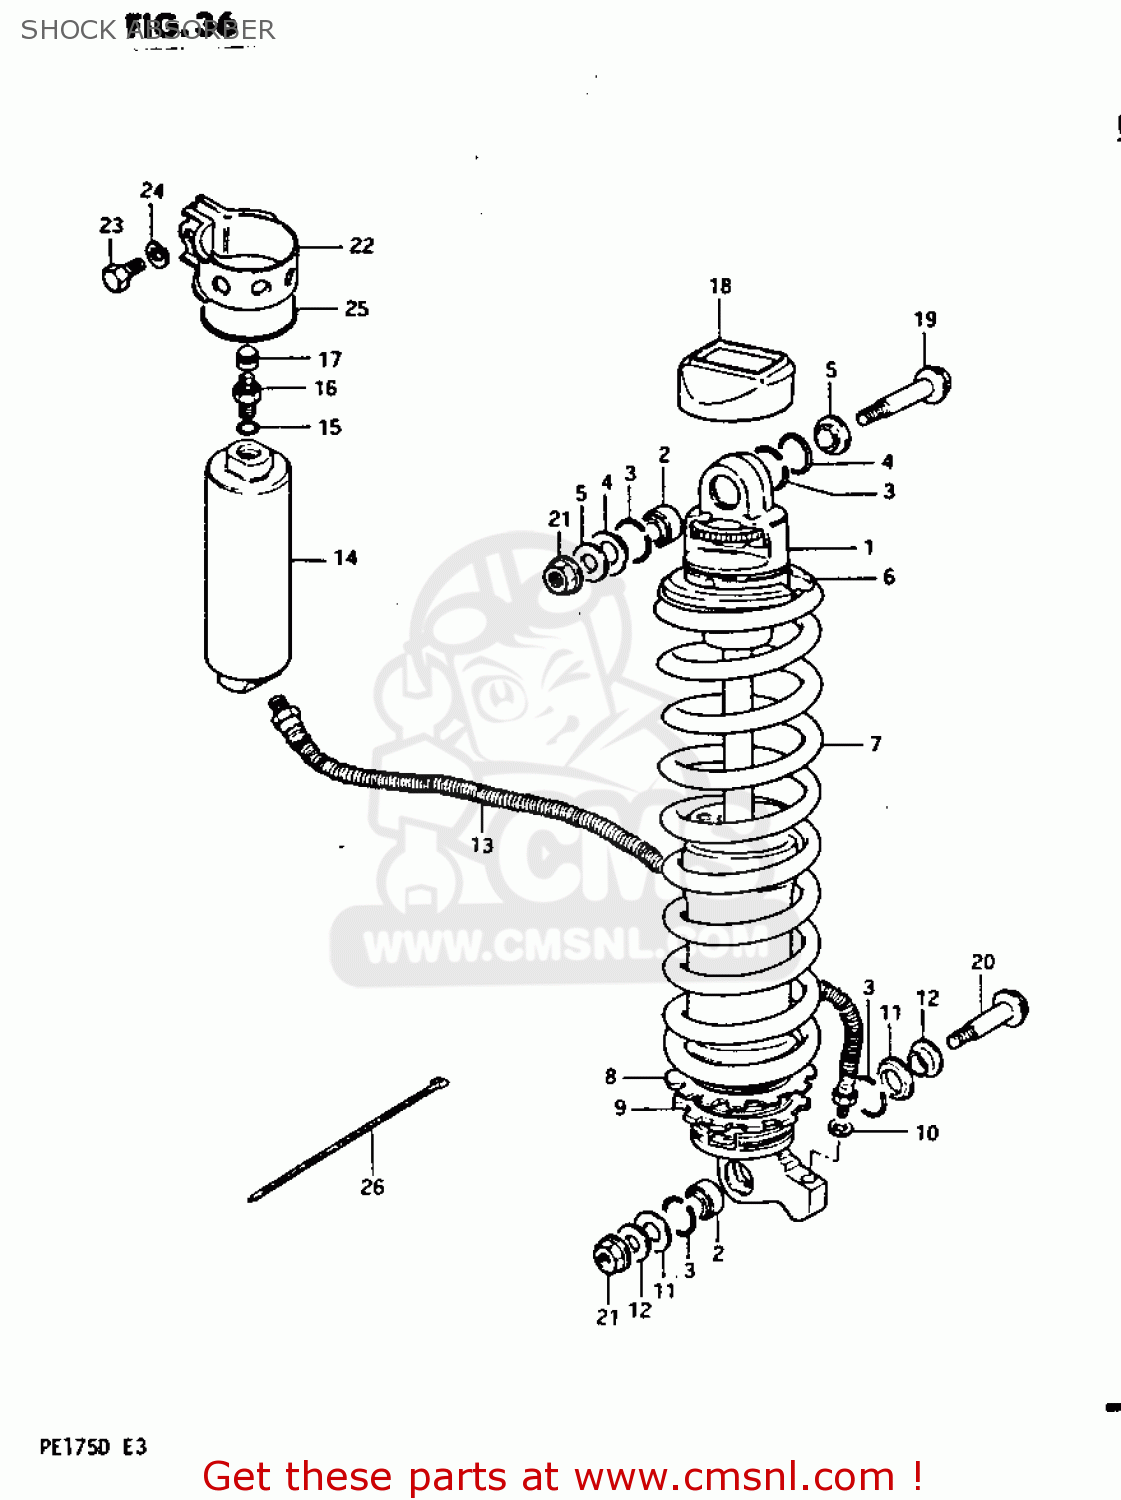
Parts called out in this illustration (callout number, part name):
1	ABSORBER ASSEMBLY,REAR SHOCK
2	SPHERICAL BEARING,REAR C
3	RING,STOP
4	O-RING,FORK INNER TUBE
5	SPACER,REAR SHOCK,UPPER
6	SPRING GUIDE
7	SPRING
8	GUIDE,SPRING
9	GUIDE,REAR SHOCK ABSORBER SPRING
10	O-RING,RESERVE TANK
11	DUST SEAL,REAR SHOCK
12	SPACER,REAR SHOCK,UPPER
13	HOSE,REAR SHOCK ABSORBER
14	RESERVE TANK,REAR SHOCK
15	O-RING
16	VALVE ASSEMBLY,REAR CUSHION
17	CAP
18	CAP
19	BOLT(10X70)
20	BOLT(10X54)
21	NUT
22	BRACKET
23	BOLT
24	LOCK WASHER
25	CUSHION,RESERVOIR TANK
26	CLAMP
